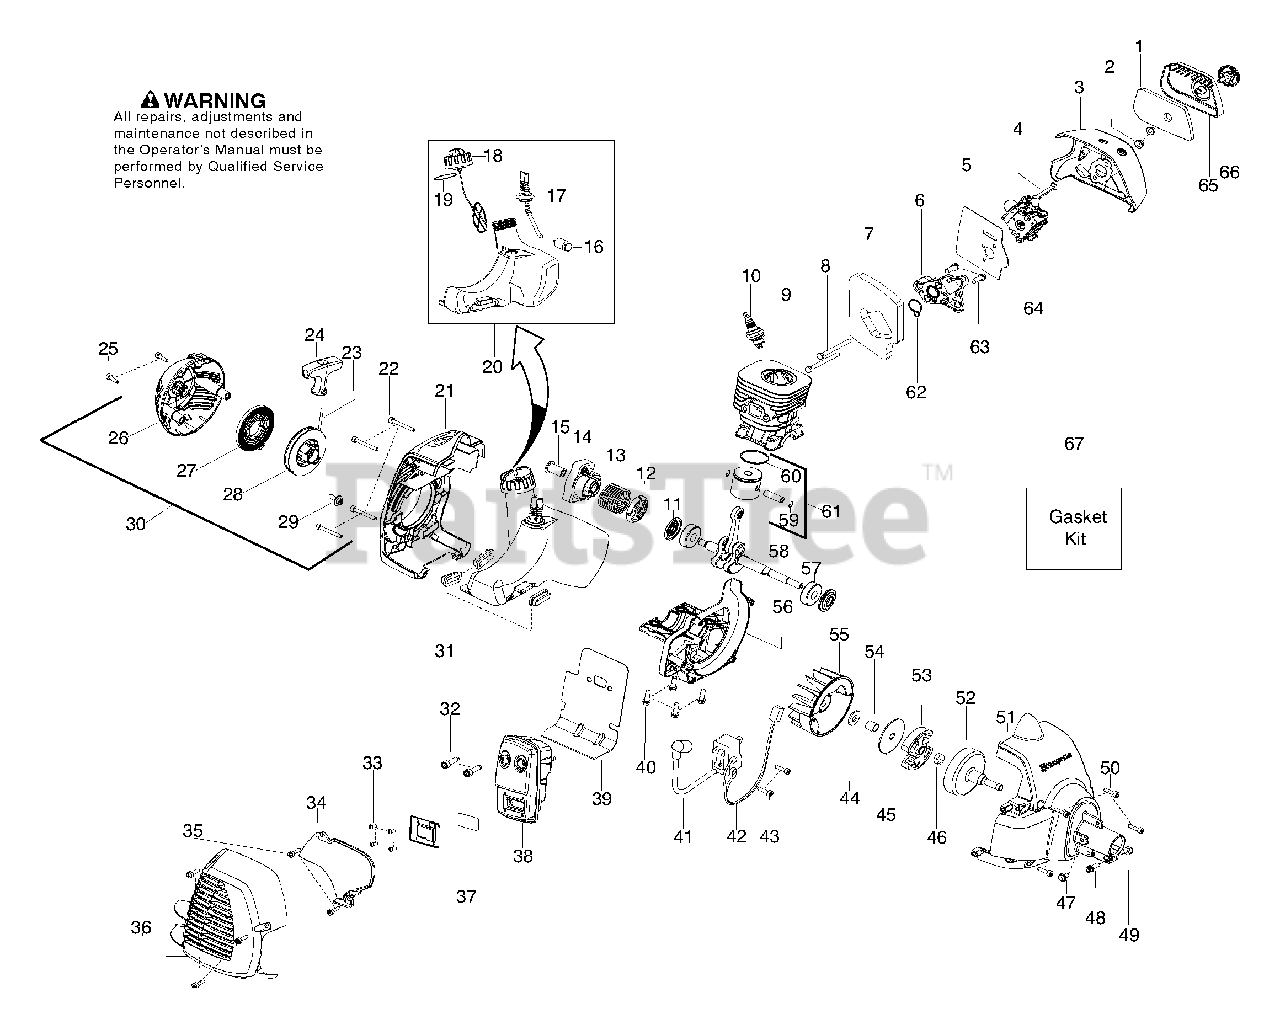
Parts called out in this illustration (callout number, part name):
2	Nut-Carb. Screw
3	Air Box
4	Kit-Choke Lever
5	Kit-Carb. Gasket
6	Adaptor-Carb.
7	Kit-Gasket (foam)
9	Cylinder
10	Plug-Spark (RCJ-6Y)
11	Kit-Crankshaft seal
12	Washer-Starter
13	Spring-Starter Cup
14	Assy-Starter Cup
15	Coupling-Starter
16	Assy-Fuel Filter
17	Kit-Fuel Line
18	Assy-Cap w/ret.
19	O-ring - Fuel Cap
20	Assy-Fuel Tank
21	Shroud-Rear
24	Handle-Starter
26	Starter Hsg.w/eyelet
27	Kit-Starter Spring
28	Kit-Starter Pulley
30	Assy-Starter Hsg.
31	Isolator-Tank
32	Bolt-Muffler
34	Shield-Heat
36	Guard-Muffler
37	Kit-Spark Arrestor
38	Assy-Muffler
39	Gasket-Paper Metal
41	Module
42	Assy-Leadwire
45	Washer-Clutch
46	Spacer-Clutch
51	Assy-Fan Housing
52	Assy-Clutch Drum
53	Assy-Clutch
56	Crankcase-Machined
58	Kit-Crankshaft
59	Retainer-Piston Pin
60	Ring-Piston
61	Kit-Piston
62	Kit-Gasket (adaptor seal)
64	Kit-Carb.
65	Cover-Air Box
67	Kit-Gasket
